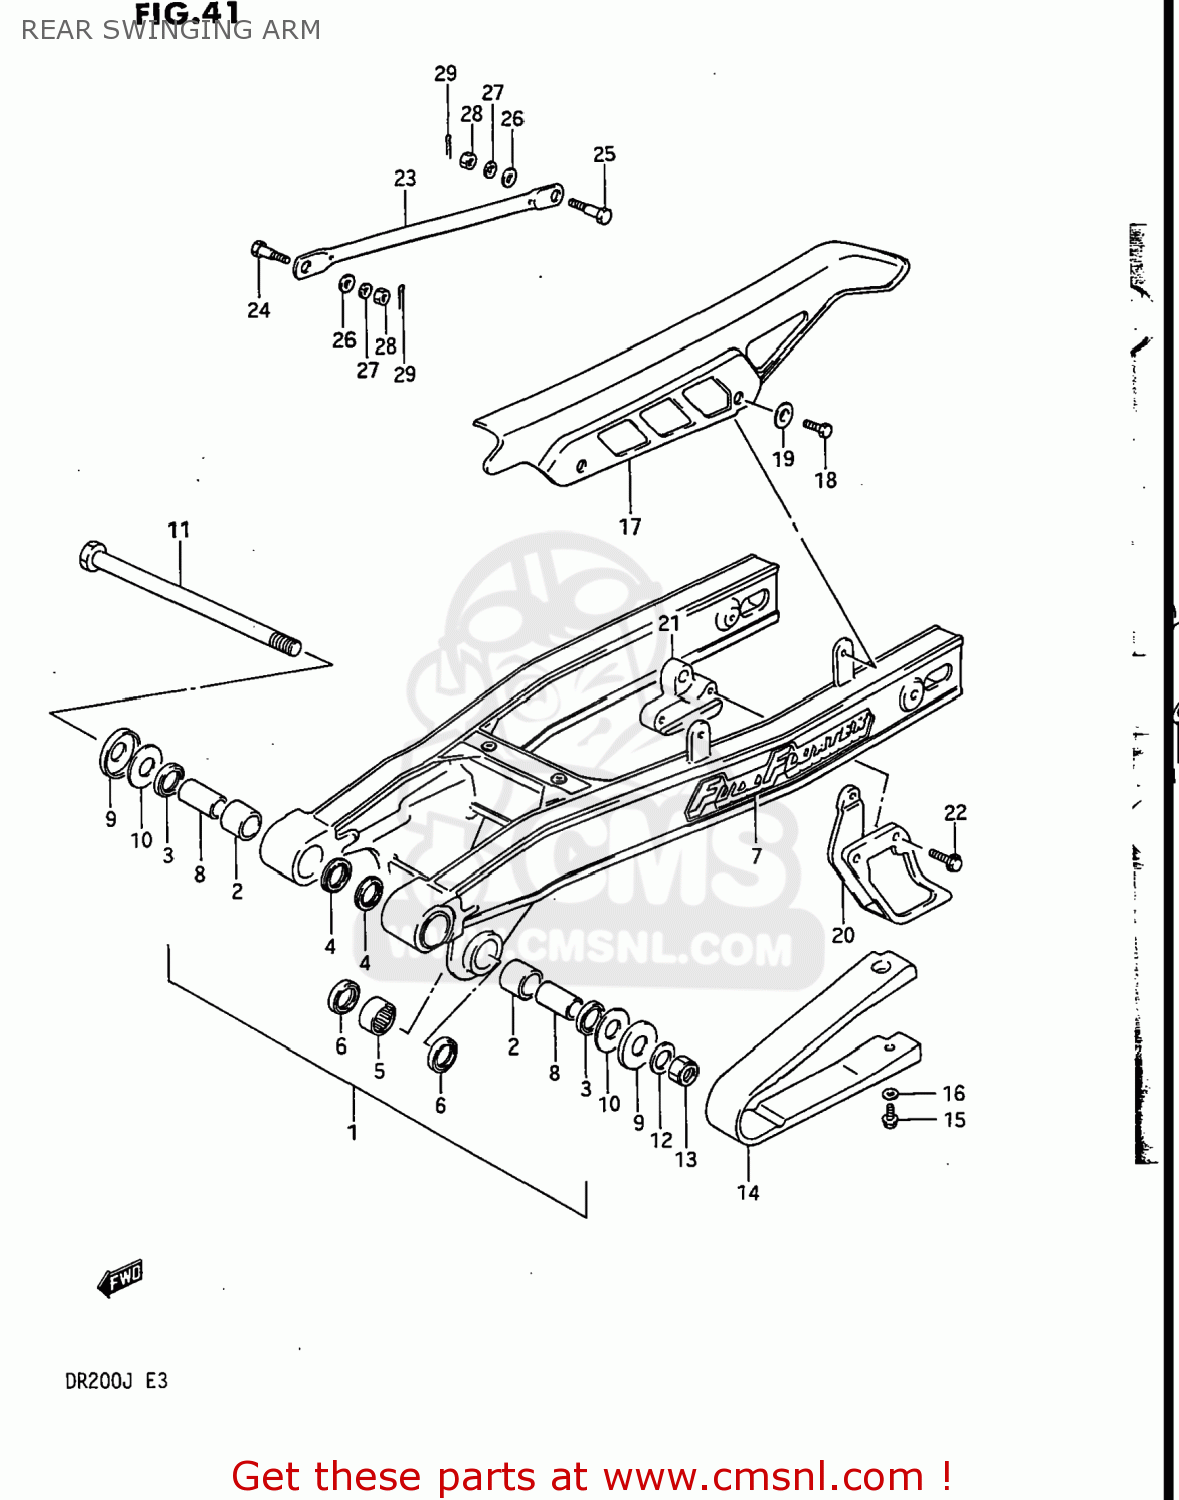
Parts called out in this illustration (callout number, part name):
1	SWING ARM ASSEMBLY,REAR
2	BUSHING,RR SWGARM PIVOT
3	OIL SEAL
4	SEAL,OIL(20X27X5)
5	BEARING
6	SEAL,CUSHION LEVER OUT DUST
7	EMBLEM
8	SPACER,RR SWGARM PVT
9	COVER,RR SWGARM DUST SEAL
10	WASHER
11	SHAFT,REAR SWING ARM
12	WASHER
13	NUT
14	BUFFER,CHAIN TOUCH DEFLECTOR
15	BOLT
16	WASHER
17	CASE,CHAIN
18	BOLT
19	WASHER
20	GUIDE,CHAIN
21	RUBBER,CHAIN GUIDE
22	BOLT
23	TORQUELINK,RR
24	BOLT,TORQUE LINK,FRONT
25	BOLT(8X26.5)
26	WASHER
27	LOCK WASHER
28	NUT
29	PIN 20X20
